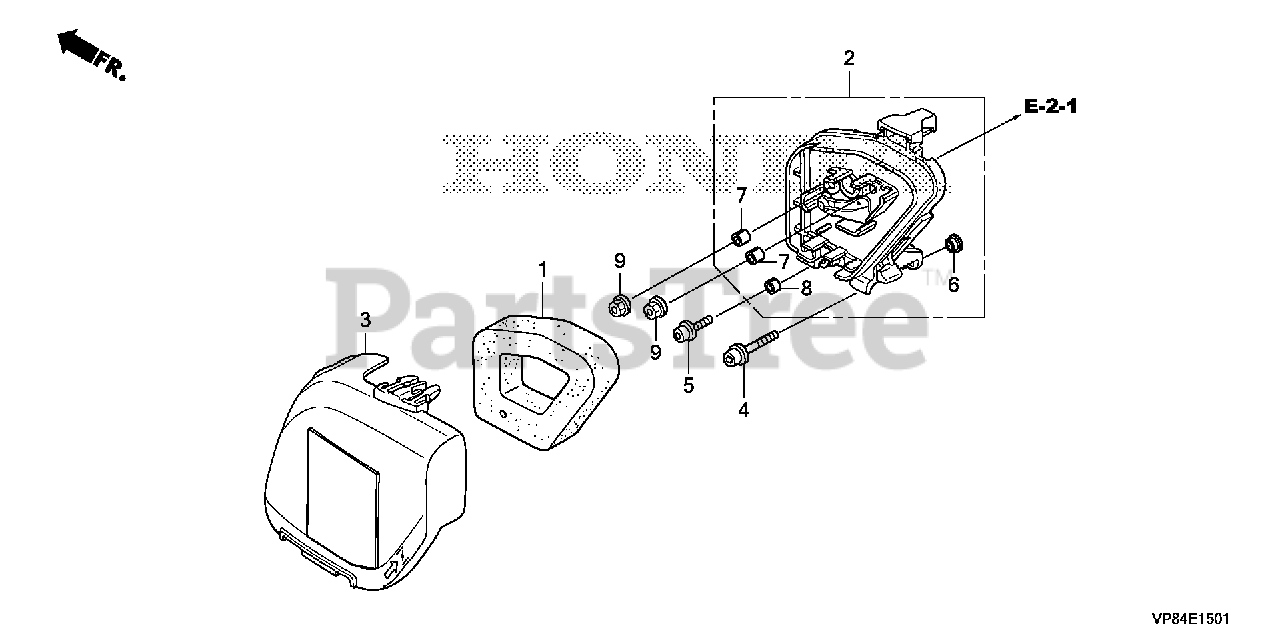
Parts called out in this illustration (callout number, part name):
1	ELEMENT, AIR CLEANER
2	HOUSING, AIR CLEANER
3	COVER, AIR CLEANER
4	BOLT, SOCKET (5X25)
5	BOLT, SOCKET (5X16)
6	COLLAR, AIR CLEANER HOUSING
7	COLLAR, AIR CLEANER
8	COLLAR A, HEAD COVER
9	NUT, FLANGE (5MM)
